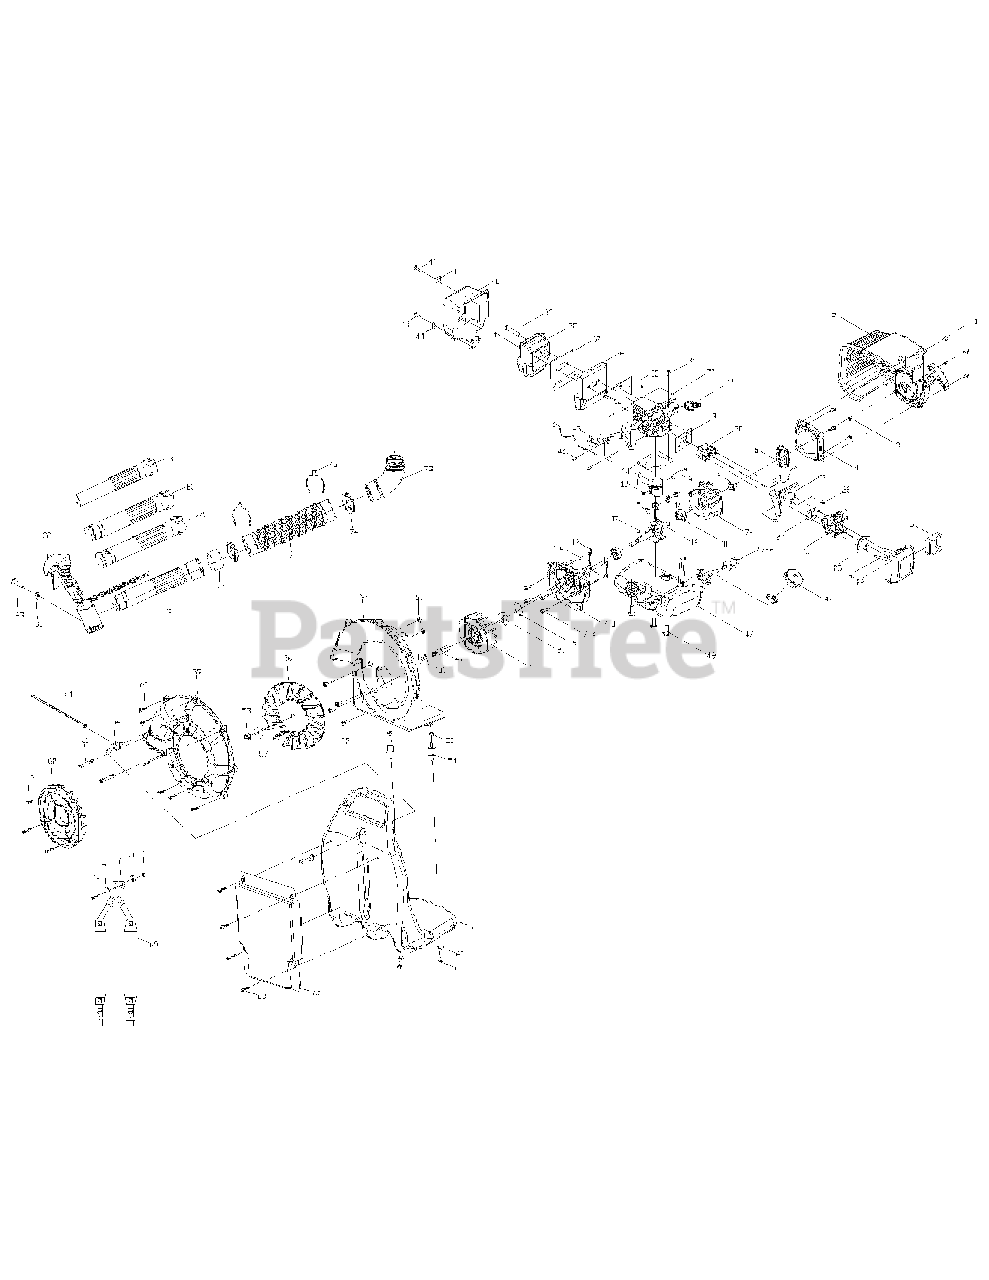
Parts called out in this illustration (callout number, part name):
2	STARTER HOUSING ASS'Y
4	CONNECTOR
5	PAWLS ASS'Y
7	CRANK CASE ASS'Y
8	BALL BEARING
11	PISTON RING
12	CLIP, PISTON
13	GASKET, CYLINDER
14	NEEDLE BEARING
15	SPACER, PISTON
16	CRANK/ROD ASS'Y
17	KEY, FLYWHEEL
18	C'CASE GASKET
19	C-CLIP
22	AIR CLEANER ASS'Y
23	FILTER, AIR
25	O-RING, AIR
26	CARBURETOR
27	CARBURETOR GASKET
30	INSULATOR
31	GASKET, INSULATOR
35	GASKET, MUFFLER
36	MUFFLER HEAT SHIELD
37	MUFFLER HEAT SHIELD
40	BAFFLE, MUFFLER
45	IGNITION ASS'Y
47	FUEL TANK ASS'Y
47-1	OIL CAP
47-2	FILTER, OIL
49	CONNECT AXIS
52	SCREW HOUSING
54	VIBRO-ISOLATING RUBBER
59	SCREW HOUSING
63	SCREW
67	CUSHION BACK
68	RIVET RIBBED
73	ELBOW PIPE1
74	HOSE BEND
75	WIRE CLAMP
76	FLEX PIPE
77	ACTIVERING
78	BASE PIPE
79	MIDDLE PIPE
82	THROTTLE LEVER ASS'Y
84	LIGATE TAPE
